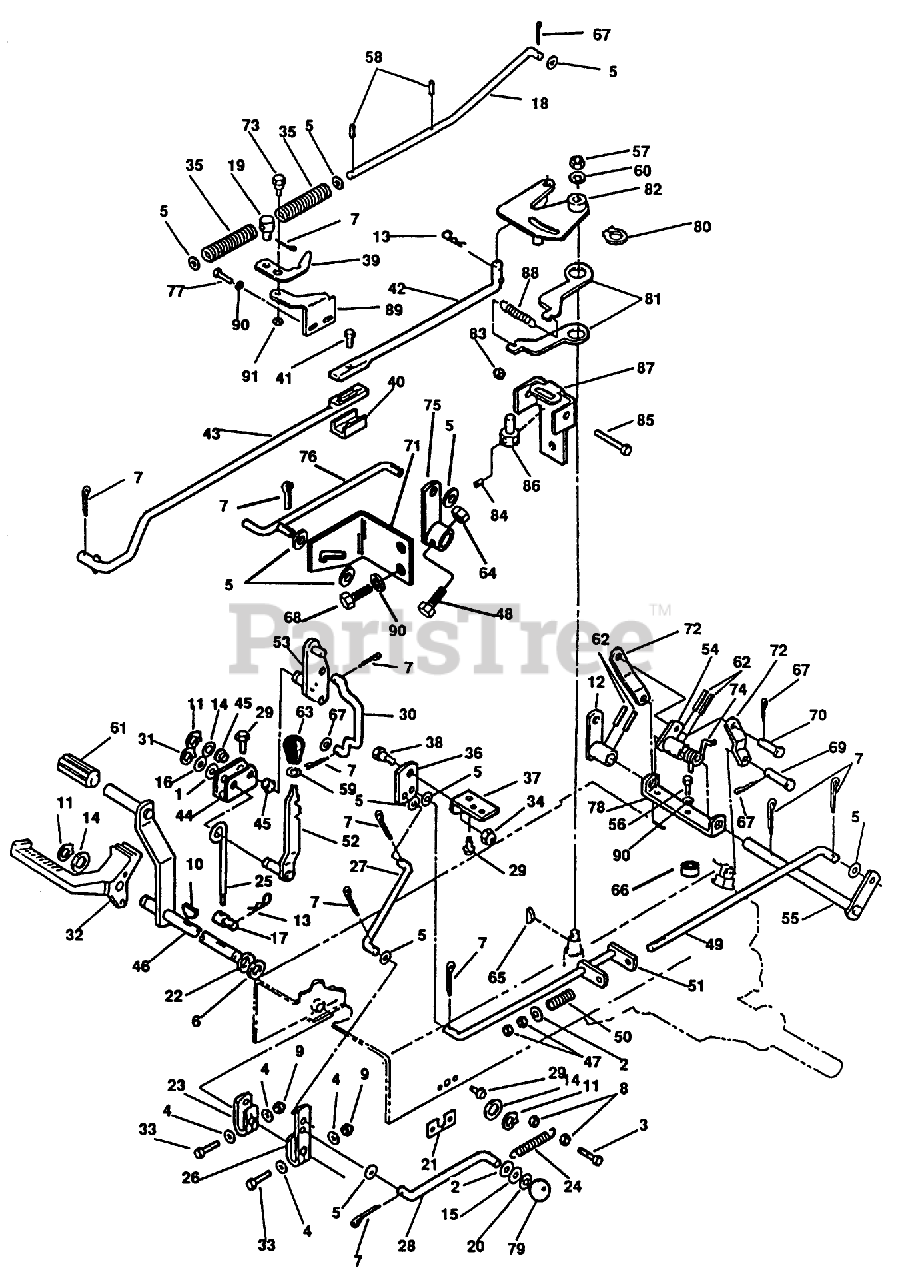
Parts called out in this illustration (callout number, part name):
9	NUT-LOCKING
13	PIN-HAIR
22	WASHER-CUPPED
31	RING - RETAINING
37	BRKT-BRAKE PIVOT
49	LINK-BRAKE SPRING
52	CRUISE RELEASE AY.
56	SCREW - HEX
68	SCREW-THD ROLL, HWH
72	PLATE - BRAKE CLEVIS
73	BOLT-SHOULDER
74	SPRING,TORSION
78	BRACKET
80	RING - RETAINING
84	SETSCREW
88	SPRING-EXTENSION
89	BRACKET-LOCK
